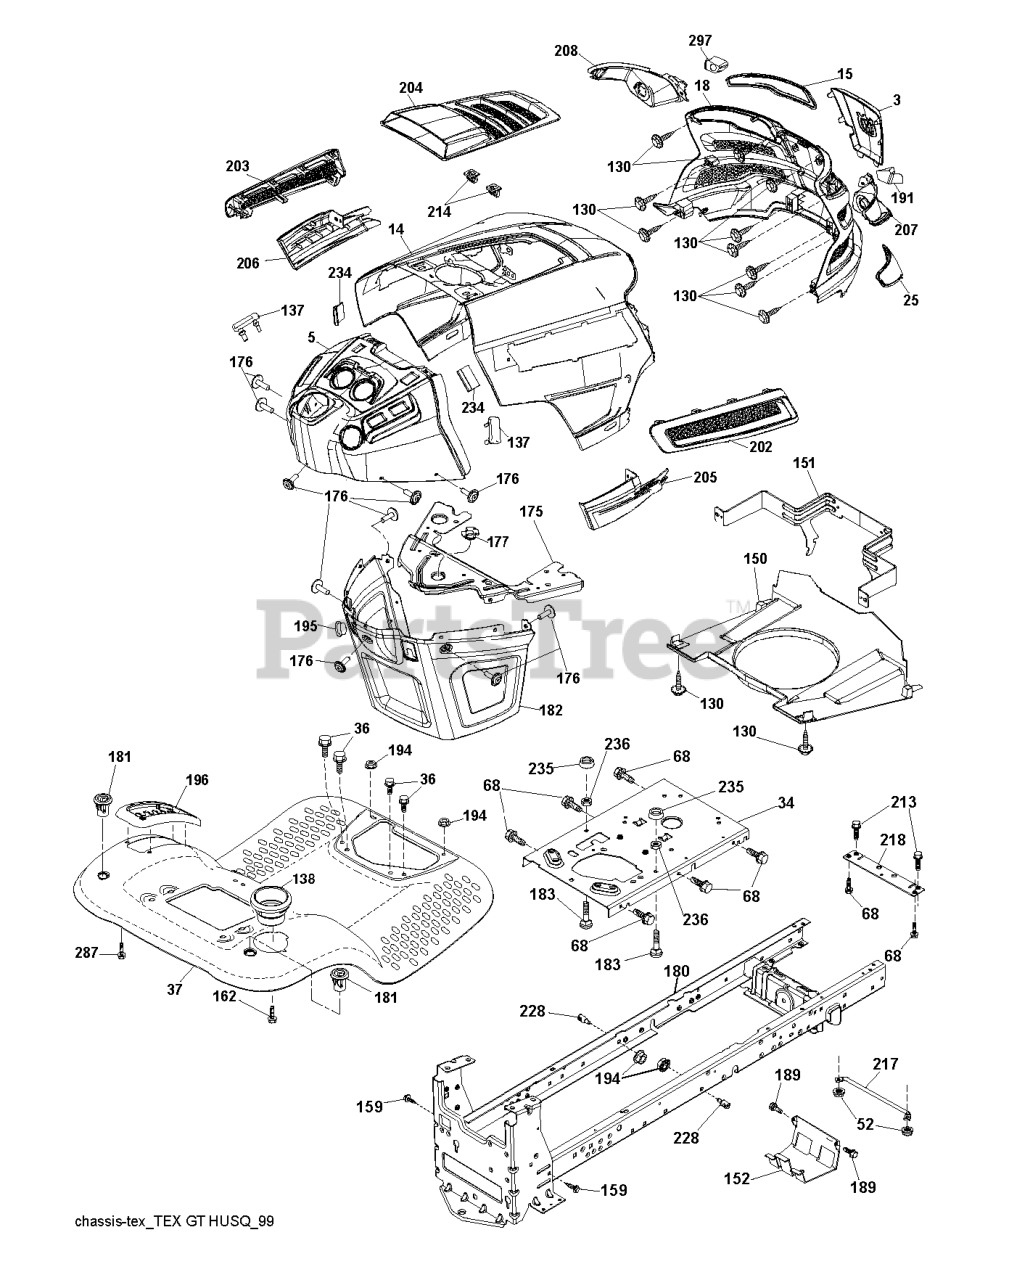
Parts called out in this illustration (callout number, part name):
3	APPLIQUE.SUBASM.GT.HUSQ.II
5	RP.DASH.UPP.GT2.SM.MC.CHOKE
14	HOOD.ASM.HUSQVARNA.GT.TEX.ORAN
15	LENS.HEADLIGHT.LH.GTII.2011
18	GRILLE.SUBSTRATE.2011.
25	LENS.HEADLIGHT.RH.GTII.2011
34	PLATE.ENGINE.WELDED.CHASSIS
36	SCREW 5/16"
37	FENDER.TLT.PDL.CNTRL.W/CPH.ORG
52	LOCKNUT
68	Screw 5/16-18 x 1/2 Hex, Self Tapping 5/16-18 x 1/2
130	SCREW.#10 X 0.750.BOS
137	BUMPER DASH
138	HOLDER.CUP.LT.GREY
150	AIR DUCT.GTV2(1.66"RING HEIGHT
151	BRACKET.PIVOT.HOOD.GT.HUSQ.II
152	SHIELD.BROWNING.W/TEX
159	SCREW, 3/8-16X3/4
162	SCREW.HI-LO.CONSOLE
175	PLATE.CROSSMEMBER.HUSQ
176	SCREW.#10-24X5/8.RN.QU
177	BUSHING, STEERING
180	CHASSIS
181	BUSHING.MNT.FEND.CRGO.TEX.49
182	DASH.LOWER.COMMON.12V.ADAPTOR
183	BOLT.5/16-18X1-1/4 FULL THD
189	SCREW
191	INSERT.REFLECTIVE.RH.HUSQ.GTII
194	NUT LOCK HEX FLANGE 5/16-18
195	PLUG.HOLE.DASH.LOWER.12V.BLK
196	DECKLFT.CONSOL FULL ASSM GREY
202	VENT.SIDE.RH.GT.HUSQ.II.
203	VENT.SIDE.LH.GT.HUSQ.II.498
204	VENT.TOP.HUSQ.GT2
205	SIDE.TRIM.RH.GT.HUSQ.II
206	SIDE.TRIM.LH.GT.HUSQ.II.GRAY
207	BEZEL LIGHT.RH.GT.II.MYLAR
208	BEZEL LIGHT.LH.GT.II.MYLAR
213	BOLT
214	CLIP.RETAINER.TINNER.
217	ROD.PIVOT.HOOD
218	X-PIECE.HOOD.STOP.NON/
228	STUD.FASTNER.W/ANTI-ROTATE
234	BUMPER.HOOD.TEX.HUSQVARNA
235	SPACER FENDER
236	NUT.CENTERLOCK.5/16-
287	SCREW 1/4X20
297	INSERT.REFLECTIVE.LH.HUSQ.GTII
